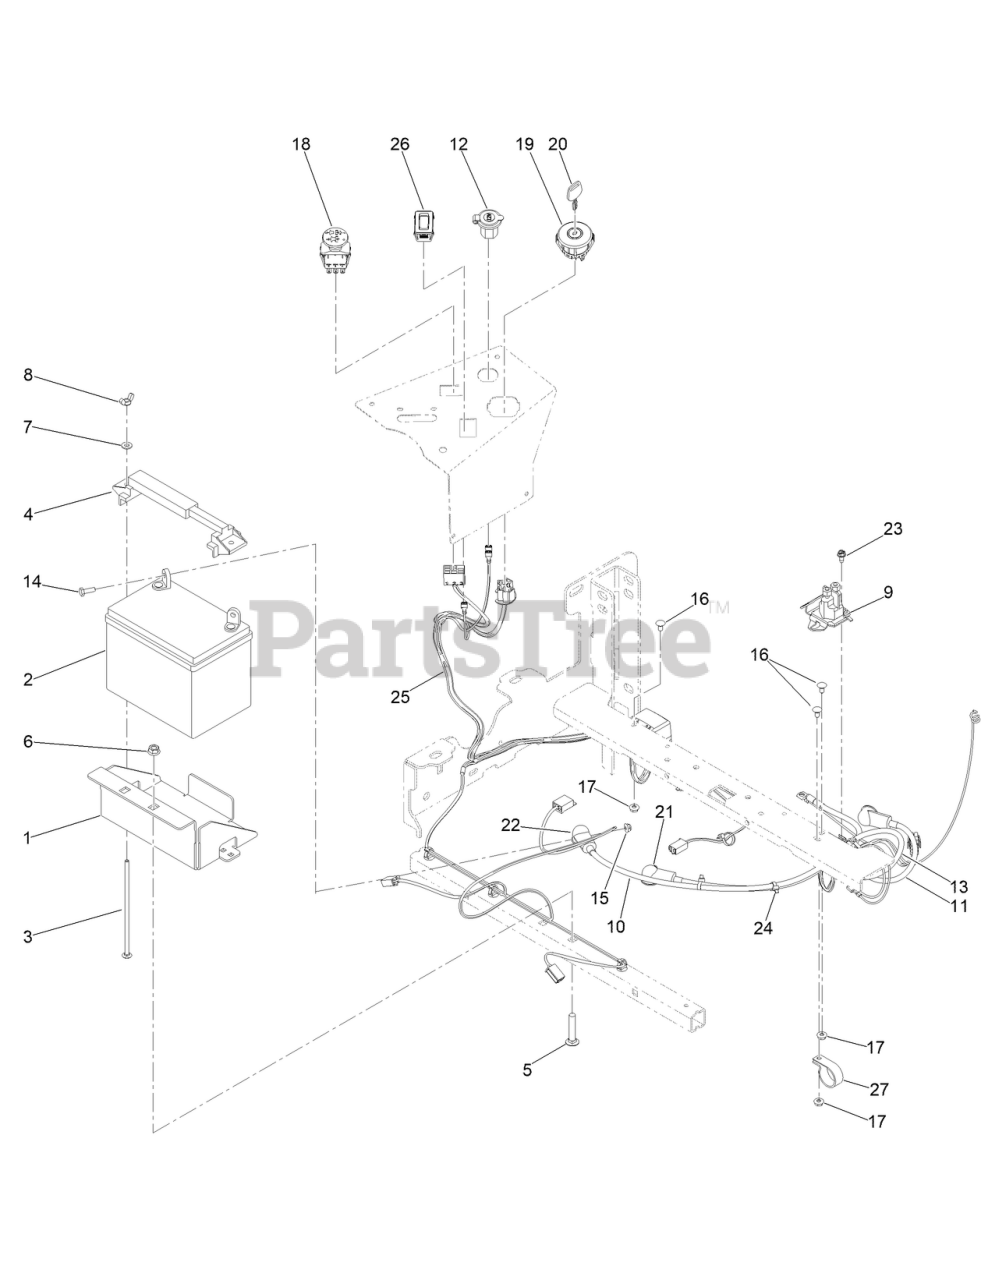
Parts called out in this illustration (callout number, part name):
1	MWR BATTERY BOX
2	12 VOLT START BATTERY 300CCA
3	1/4-20 X 7 CARRIAGE BOLT ZINC
4	BATTERY HOLD DOWN
5	SCREW-CARR
6	3/8-16 HEX FLANGE NUT W/SERR ZINC YELLOW
7	WASHER-FLAT
8	NUT-WING
9	HEAVY DUTY START SOLENOID
10	MWR NEGATIVE CABLE 28
11	MWR START WIRE 12
12	12 VOLT AUXILLIARY PLUG
13	MWR POSITIVE BATTERY CABLE 25IN
14	SCREW-HH
15	NUT-HF
16	SCREW-CARR
17	1/4-20 HEX FLANGE NUT
18	PTO SWITCH
19	IGNITION SWITCH
20	2023 MWR KEY
21	3.15 LGTH STRAIGHT INSUL TERM COVER RED
22	STRAIGHT INSULATING TERMINAL COVER
23	SCREW-HWH
24	TIE-CABLE
25	HARNESS-WIRE
26	HOUR METER
27	1-1/4IN CUSHIONED LOOP CLAMP BLACK
